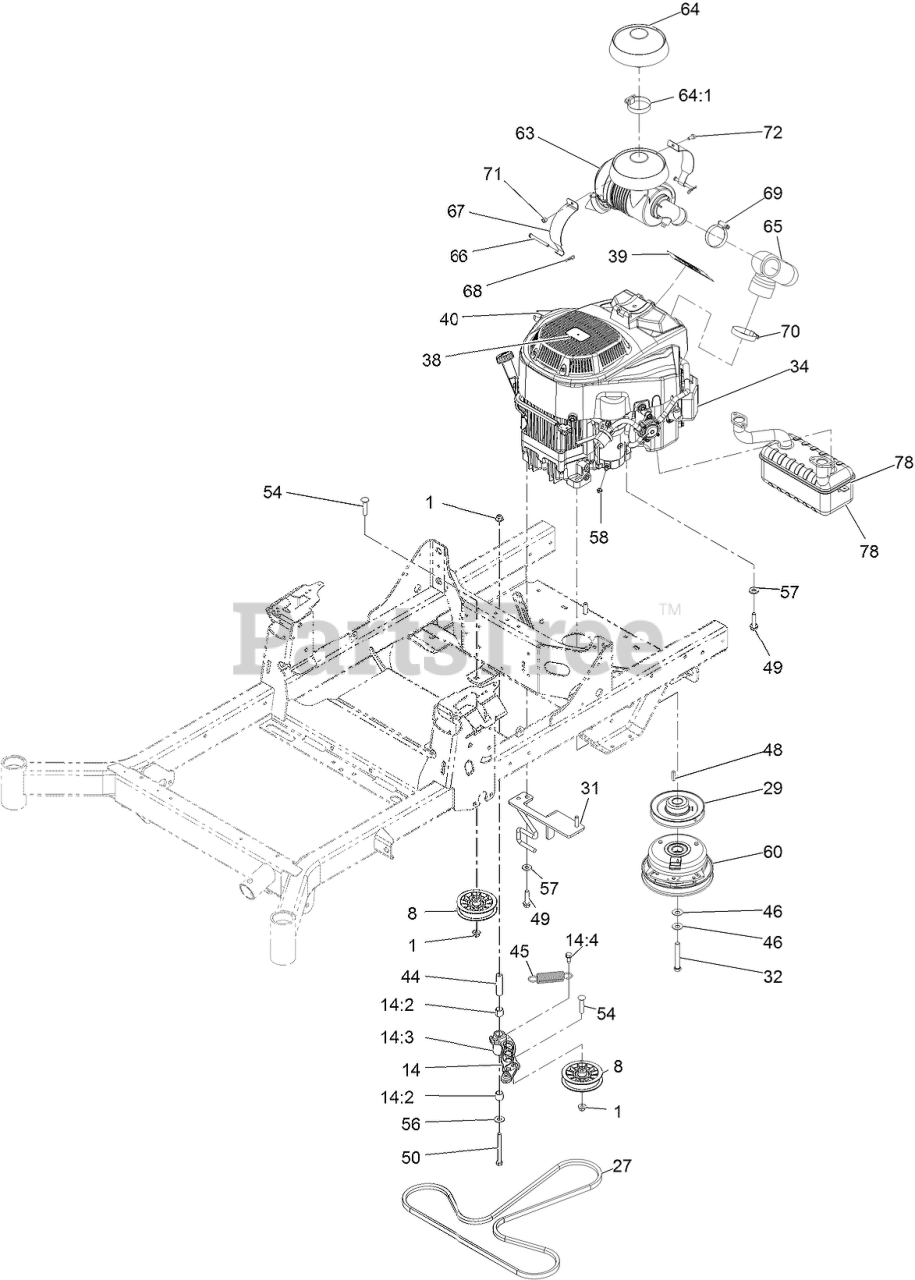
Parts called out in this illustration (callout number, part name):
1	NUT-HF, NI
8	PULLEY-FLAT IDLER
14	IDLER ARM ASM
14:2	SLEEVE-BEARING
14:3	FITTING-GREASE, 90 DEG
14:4	SCREW-THD ROLL, HWH
27	BELT-V
29	SHEAVE-ENGINE
31	ANCHOR-CLUTCH
32	SCREW-HH W/LOCTITE
34	ENGINE-2P77F-HD
39	DECAL-ENGINE 708 V-TWIN E
40	DECAL-DRAIN, OIL
44	BUSHING-PIVOT, IDLER
45	SPRING-EXTENSION
46	WASHER-SPRING
49	SCREW-HWH
50	SCREW-HH
54	SCREW-CARR
56	WASHER-FLAT
57	WASHER-BELLEVILLE
60	CLUTCH - 1.00 HD
63	AIR CLEANER ASM
64	RAIN CAP KIT
64:1	CLAMP-HOSE
65	HOSE-INTAKE
66	PIN-CLEVIS
67	STRAP-CANISTER, AIR
68	PIN-COTTER
69	CLAMP-HOSE
70	CLAMP-HOSE
71	NUT-HEX
72	SCREW-HH
78	MUFFLER
